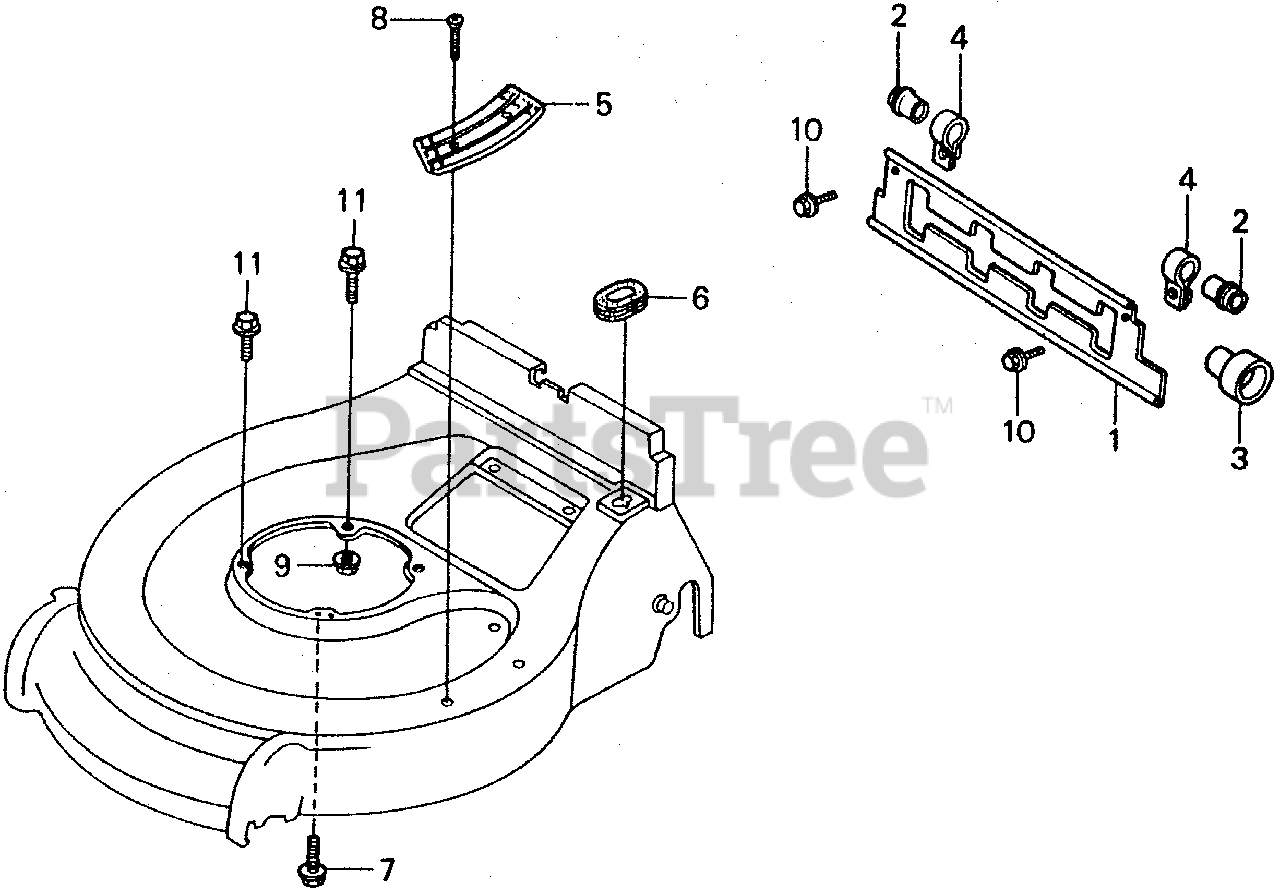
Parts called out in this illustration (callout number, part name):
1	SHIELD, RR. (NOT AVAILABLE)
2	BUSH A, RR. SHIELD
3	BUSH B, RR. SHIELD (NOT AVAILABLE)
4	STAY, RR. SHIELD (NOT AVAILABLE)
5	STEP, FOOT
6	GROMMET, CABLE
7	BOLT, FLANGE (8X16)
8	SCREW, TAPPING (5X12) (NOT AVAILABLE)
9	NUT, FLANGE (8MM)
10	BOLT, FLANGE (6X10)
11	BOLT, FLANGE (8X32)
